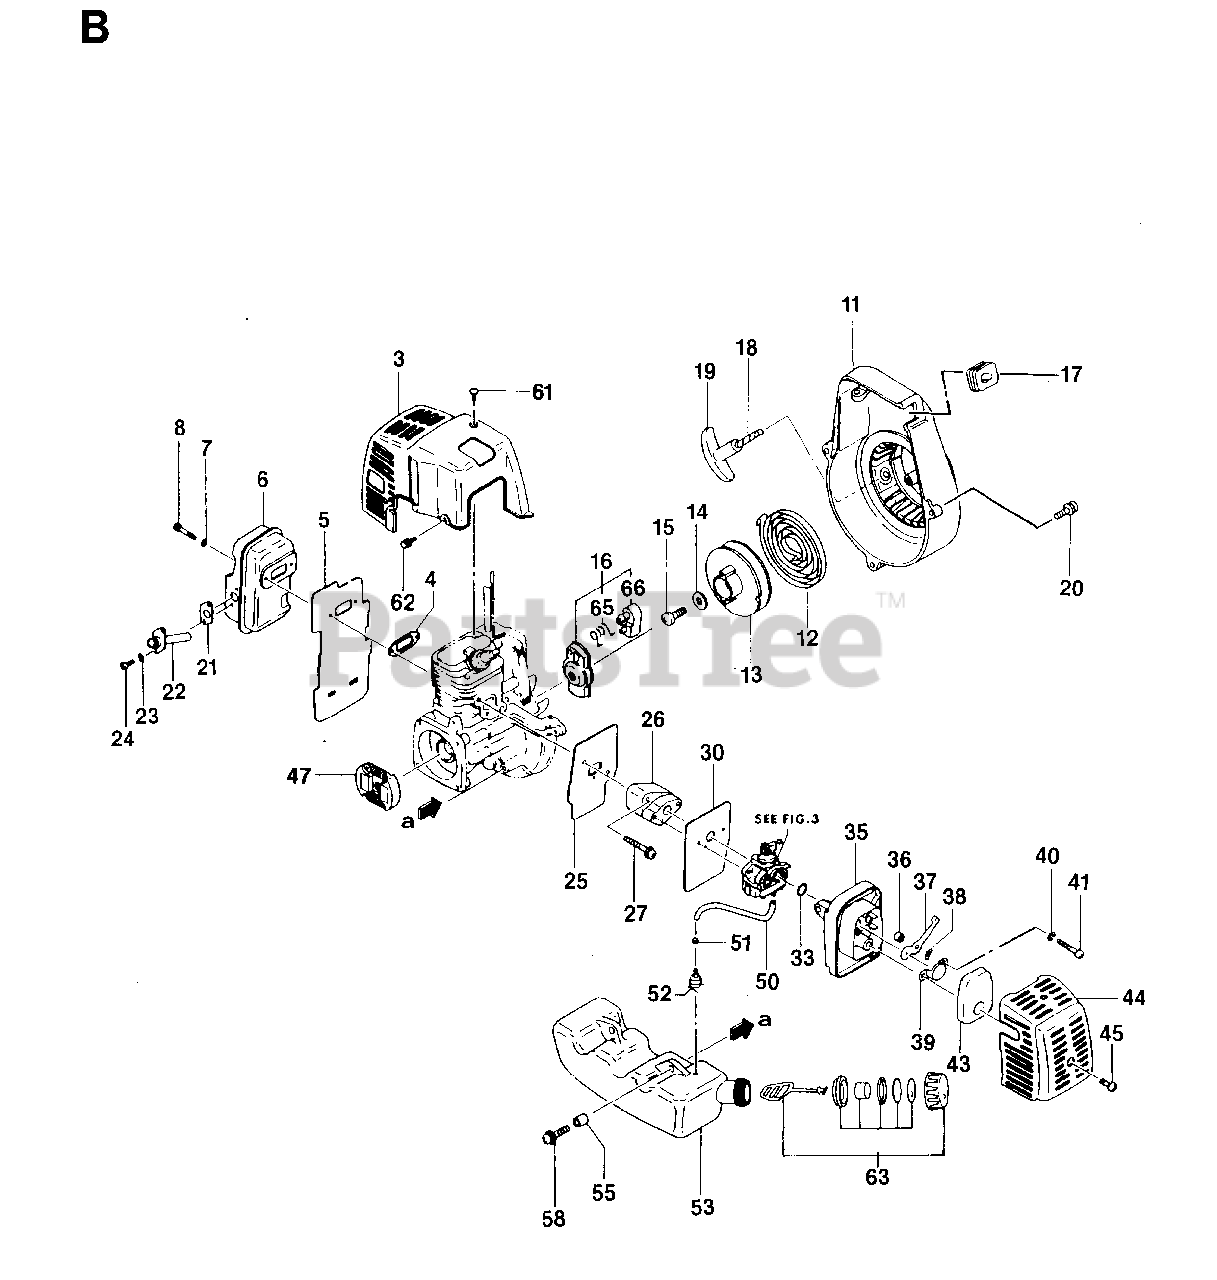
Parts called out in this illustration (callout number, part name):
7	WASHER 5.3X12
8	SCREW MC6S 5X50
23	SPRING WASHER 4.1X7.1
24	SCREW MC6S 4X8
40	SPRING WASHER
41	SCREW MC6S 5X60
